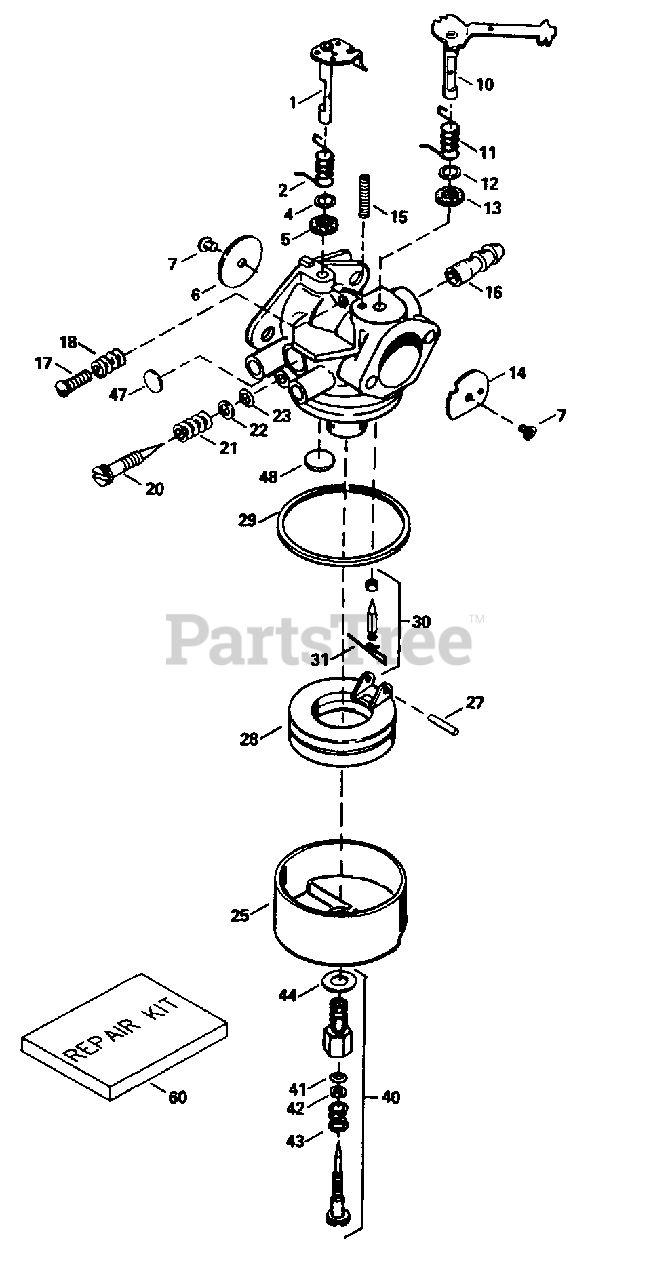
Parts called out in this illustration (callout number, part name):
1	Throttle Shaft & Lever Assembly
2	Throttle Return Spring
4	Dust Seal Washer
5	Dust Seal (Throttle)
6	Throttle Shutter
7	Shutter Screw
10	Choke Shaft & Lever Assembly
11	Choke Return Spring
12	Dust Seal Washer
13	Dust Seal (Choke)
14	Choke Shutter
15	Choke Positioning Spring
16	Fuel Fitting
17	Throttle Crack Screw/Idle Speed Screw
18	Tension Spring
20	Idle Mixture Screw
21	Tension Spring
22	Idle Mixture Screw Washer
23	Idle Mixture Screw "O"-Ring
25	Float Bowl
27	Float Shaft
28	Float
29	Float Blow "O"-Ring
30	Inlet Needle, Seat & Clip
31	Spring Clip
40	Main Adj. Screw Ass'y.
41	High Speed Mixture Screw "O"-Ring
42	High Speed Mixture Screw Washer
43	High Speed Mixture Screw Tension Spring
44	Bowl Nut Washer
47	Welch Plug, Idle Mixture Well
48	Welch Plug, Atmospheric Vent
60	Repair Kit
